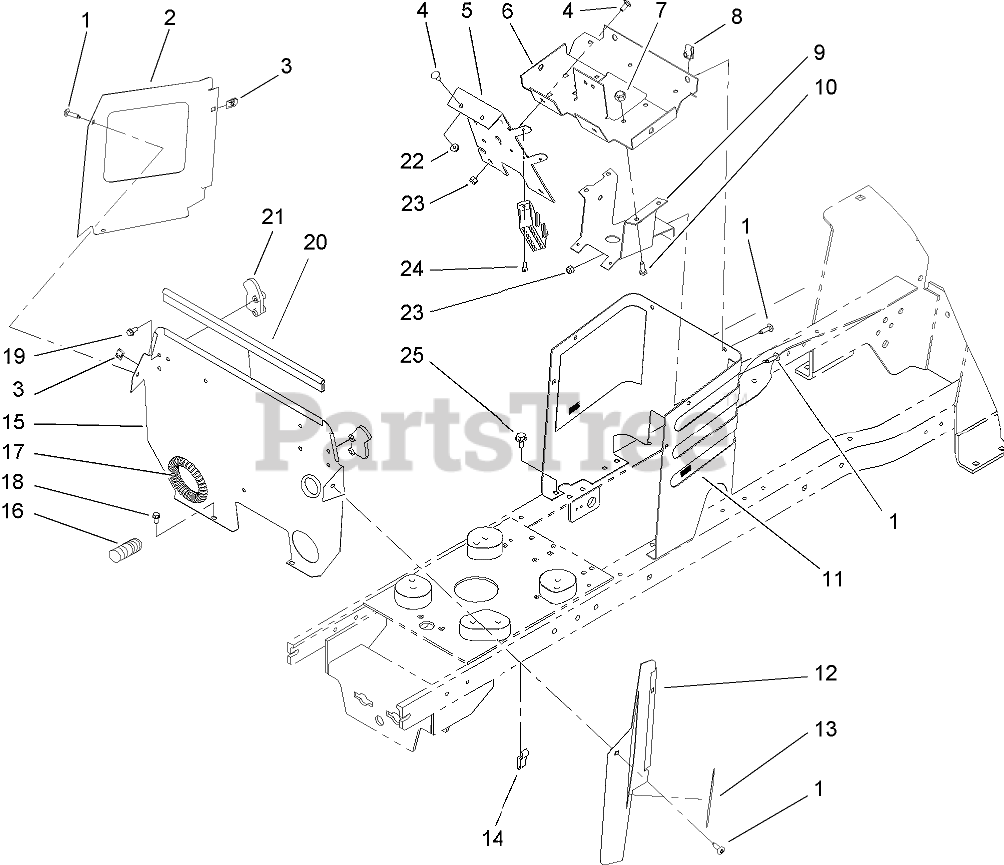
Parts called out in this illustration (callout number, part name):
1	SCREW-HH
2	RH SIDE COVER ASM
4	SCREW-CARR
5	PANEL-SUPPORT, DASH
6	SUPPORT-DASH
7	NUT-HEX
9	BRACKET-COLUMN, LOWER
10	SCREW-HH
11	HOODSTAND ASM
12	LH COVER ASM
14	CLAMP-CASING
15	FIREWALL
16	HARNESS-WIRE
17	COVER-SHAFT, DRIVE
18	SCREW-HWH
19	SCREW-PLASTITE
20	TRIM-SEAL, FIREWALL
21	LATCH-HOOD
22	NUT-KEPS
23	NUT-LOCK, NI
24	SCREW-PPHTF
25	SCREW-HWHTF
